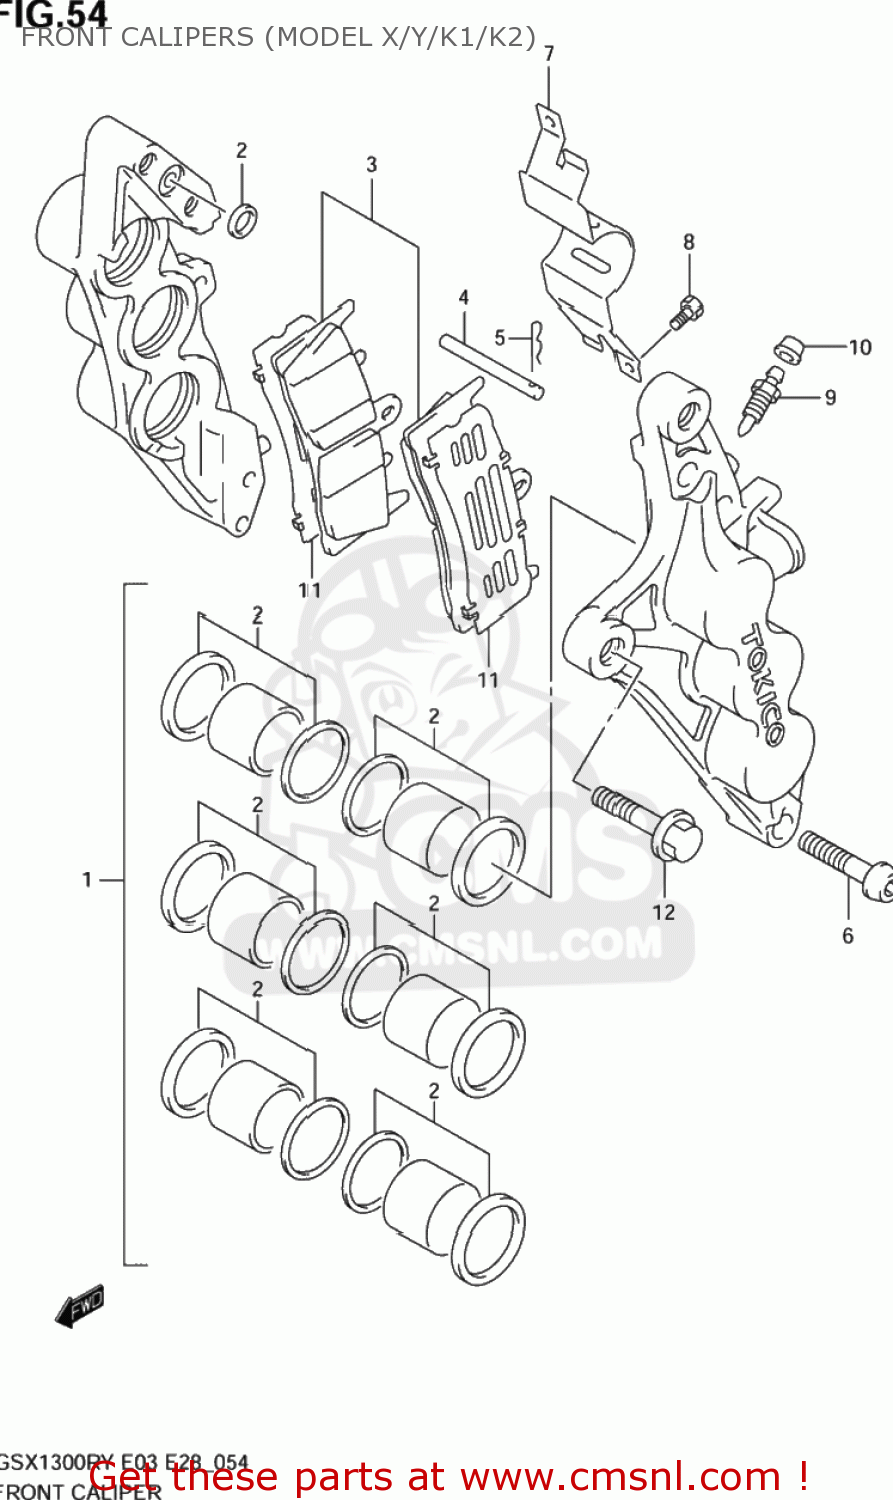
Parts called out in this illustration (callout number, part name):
1	PISTON SET
2	SEAL SET,PISTON
3	PAD SET (NAS)
4	PIN,PAD
5	CLIP,PAD PIN
6	BOLT
7	COVER,CALIPER
8	SCREW
9	BLEEDER
10	CAP,BLEEDER PLUG
11	SHIM,PAD
12	BOLT(10X30)
